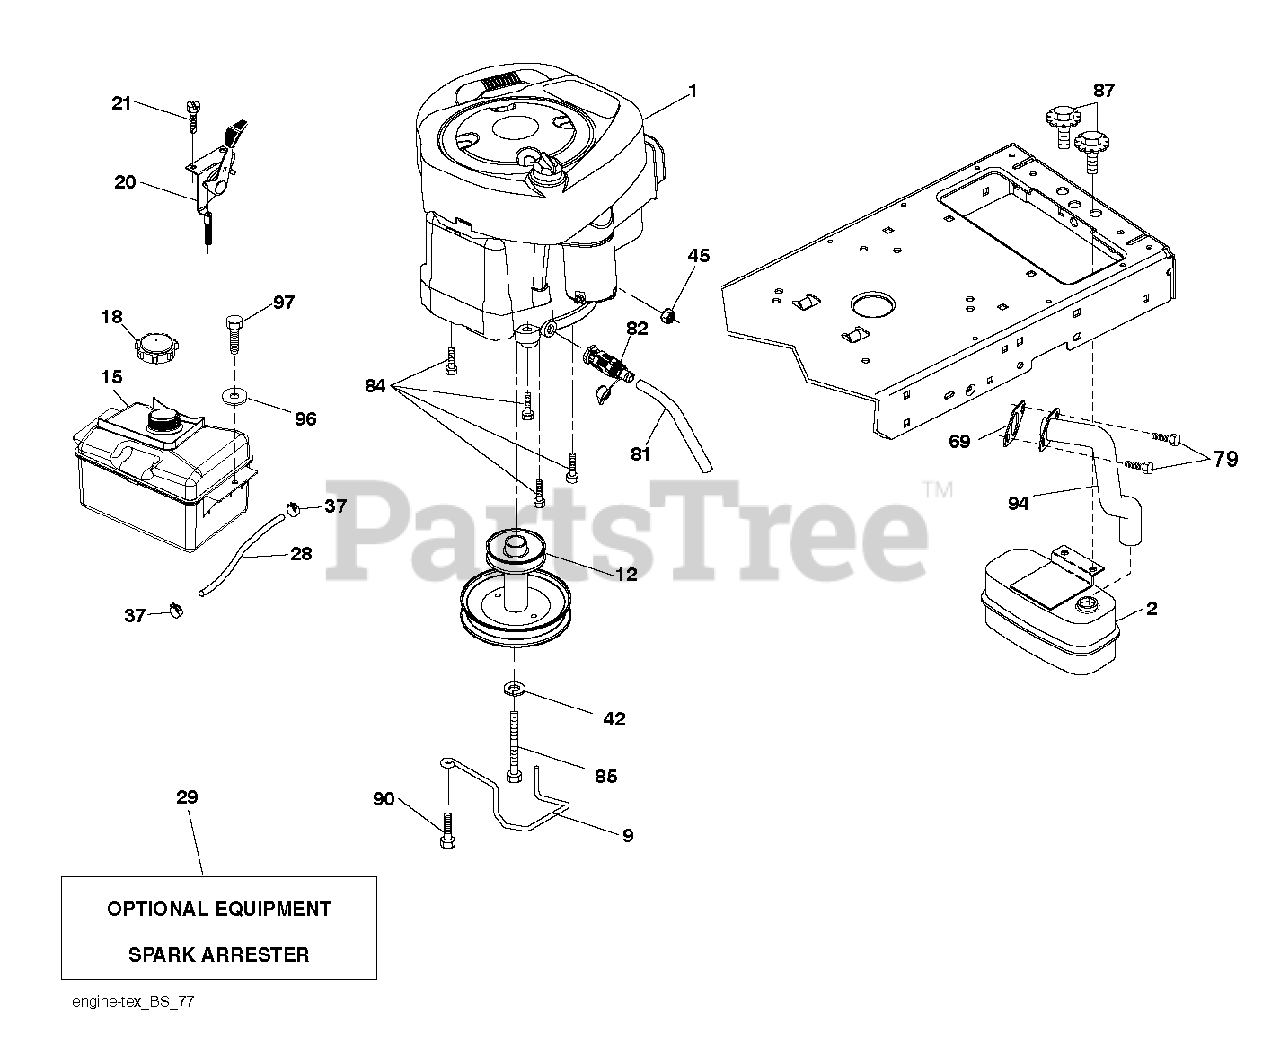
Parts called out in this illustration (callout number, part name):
2	MUFFLER.SINGLE.CYL.KOHL/B&S
9	KEEPER.BELT.ENGINE.3.25
12	PULLEY ENGINE
15	FUEL.TANK.ASM.1.5.GAL.NON-EPA
18	CAP ASM.FUEL.2.25"FR.
21	SCREW.#10 X 0.750.BOS (2 2)
28	LINE.FUEL.20"FRONT.EMI
29	SPARK ARRESTOR KIT
37	HOSE CLAMP
42	LOCKWASHER
45	NUT
79	SCREW.SOCKET HD.5/16-1
81	TUBE, DRAIN OIL ASM.
82	VALUE.OIL.DRAIN
84	SCREW.3/8-16
85	BOLT HEX 7/16-20X4-1/4"
87	BOLT, 5/16-18 X 1 3/4
90	SCREW 3/8-16X1
94	EXHAUST.TUBE.B&S.
97	SCREW HEXWSHR 1/4-20X3/4
